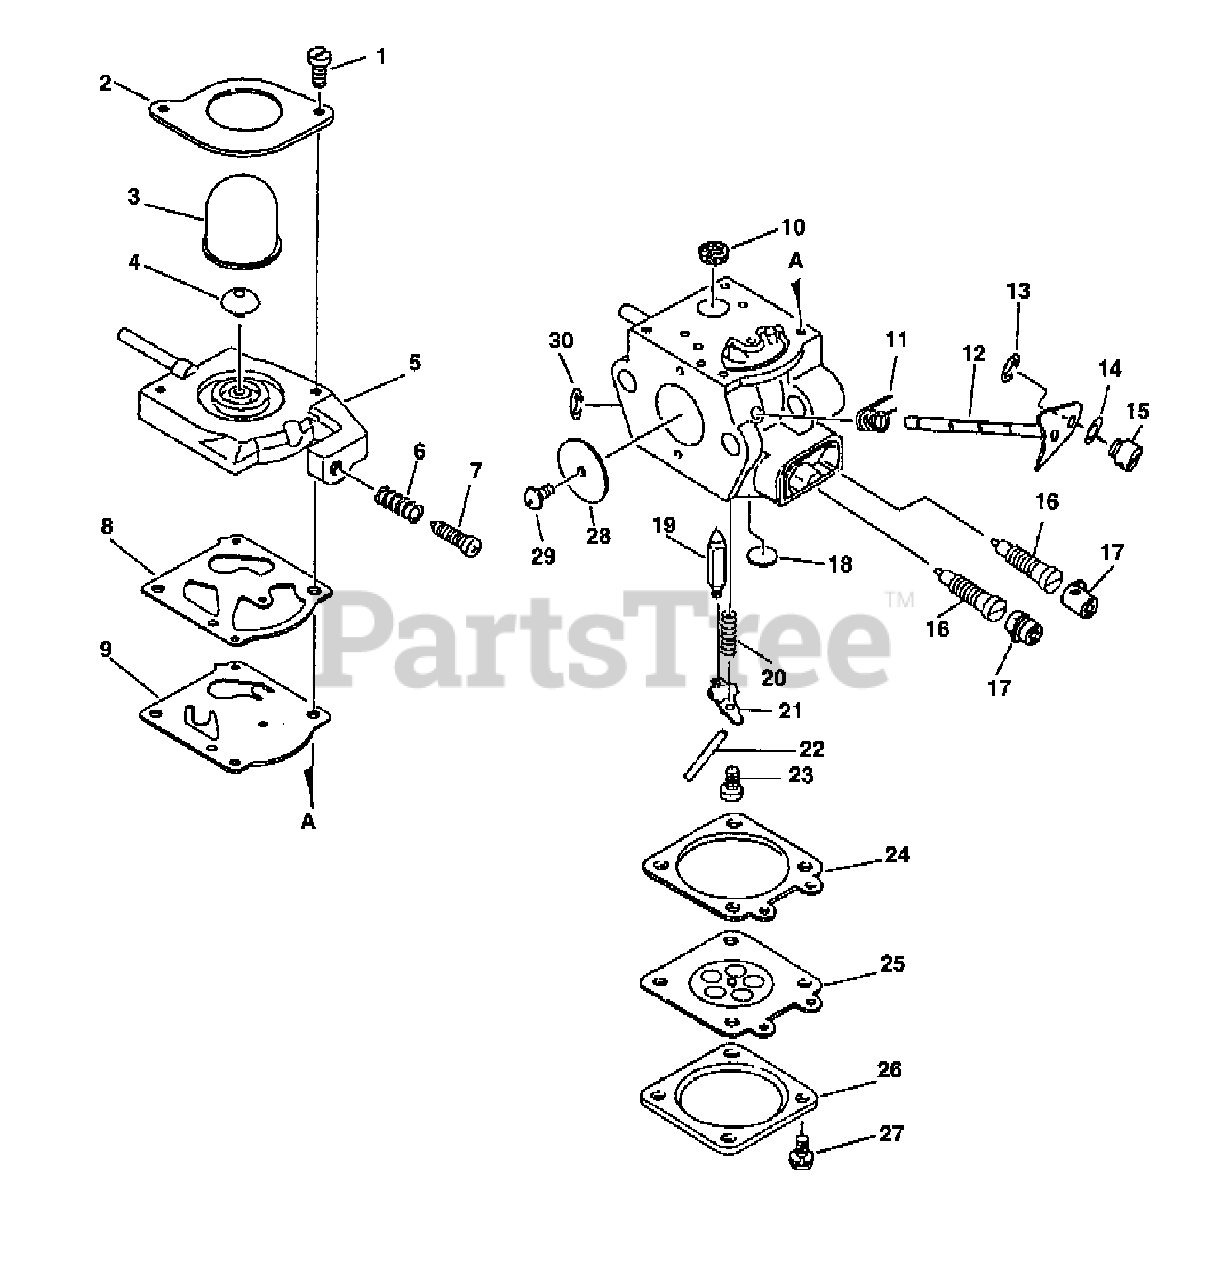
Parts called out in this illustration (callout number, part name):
1	SCREW, PUMP COVER
2	RETAINER, PURGE BULB
3	BULB, PURGE
4	VALVE, CHECK
5	BASE, PURGE
6	SPRING, IDLE ADJUST
7	SCREW, IDLE ADJUST
8	GASKET, PUMP
9	DIAPHRAGM, PUMP
10	STRAINER
11	SPRING, THROTTLE RETURN
12	SHAFT, THROTTLE
13	RING, RETAINING
16	NEEDLE - MIXTURE
17	CAP, LIMITER
18	PLUG, WELCH
19	VALVE, INLET NEEDLE
20	SPRING, METERING LEVER
21	LEVER, METERING
22	PIN, METERING LEVER
23	SCREW, METERING LEVER PIN
24	GASKET, METERING
25	DIAPHRAGM, METERING
26	COVER, METERING
27	SCREW
28	VALVE, THROTTLE
30	RING, RETAINING
30	REPAIR KIT
30	DIAPHRAGM/GASKET KIT
